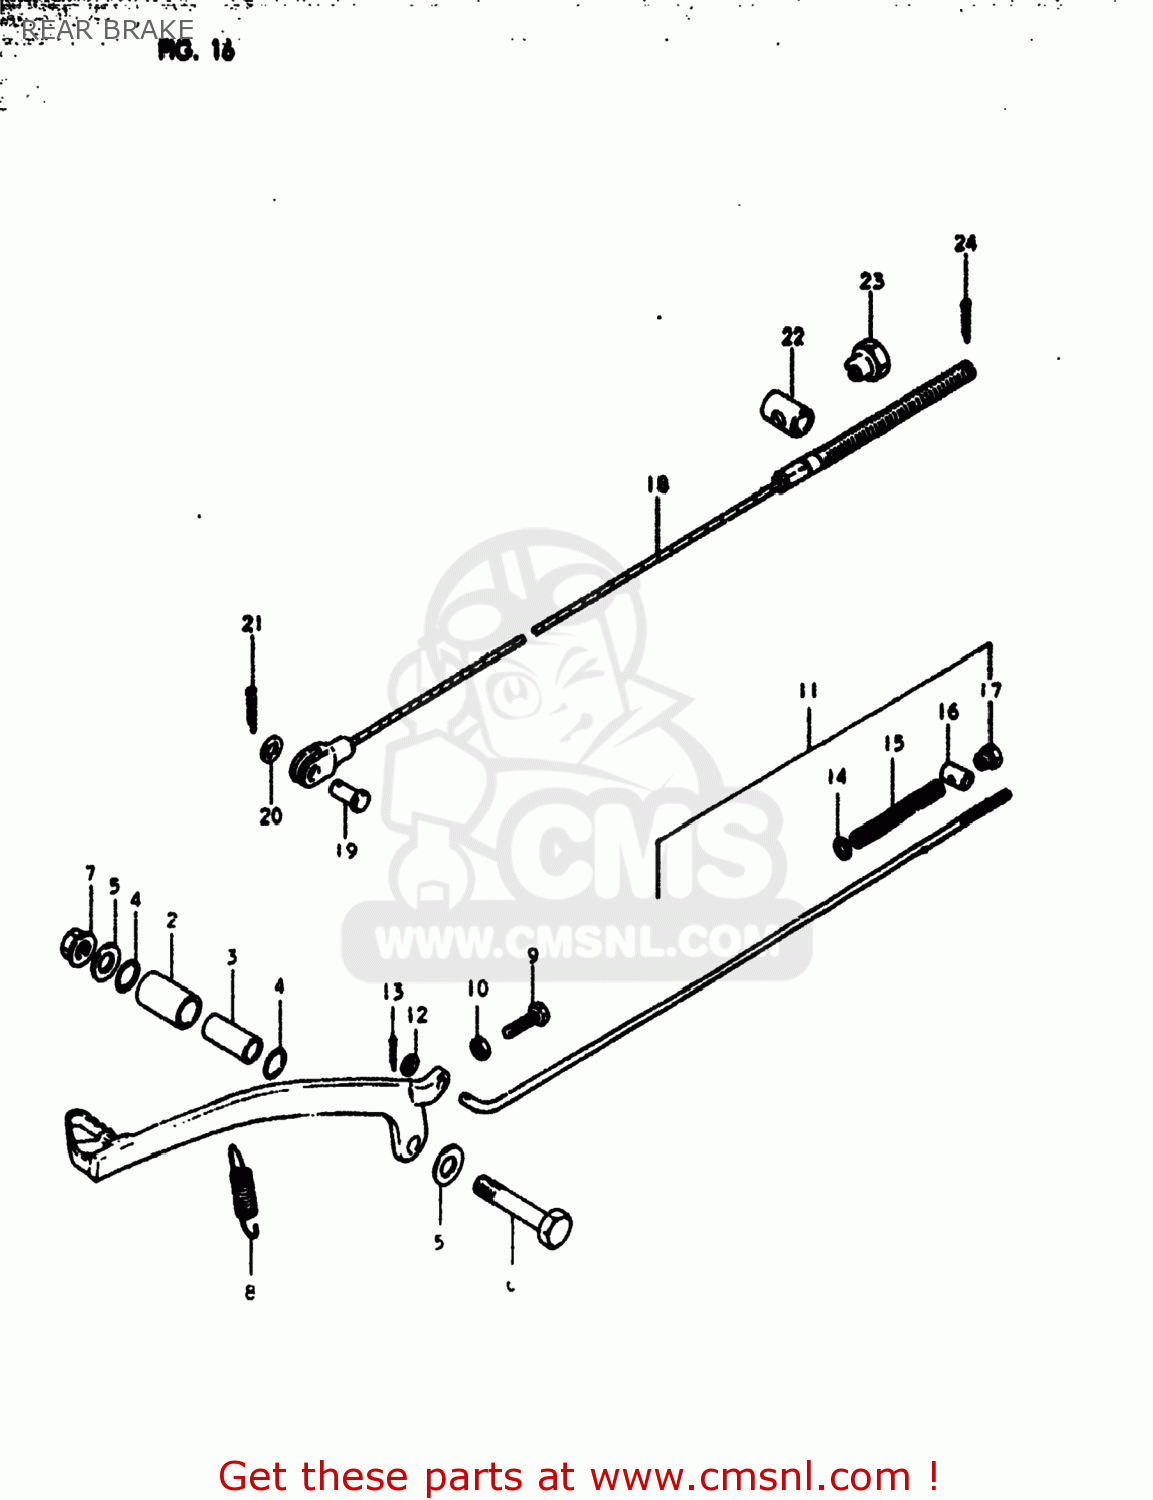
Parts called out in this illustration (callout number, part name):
1	PEDAL,BRAKE
2	BUSH
3	SPACER(10X14X32.2)
4	O RING(D:1.5,ID:13.8)
5	WASHER
6	BOLT
7	NUT
8	SPRING
9	BOLT(6X23)
10	NUT
11	ROD ASSEMBLY,REAR BRAKE
12	WASHER
13	PIN 20X20
14	WASHER
15	SPRING
16	PIN
17	NUT
18	CABLE,RR BRAKE
19	PIN(L:17.5)
20	WASHER
21	PIN 20X20
22	PIN
23	NUT
24	PIN
